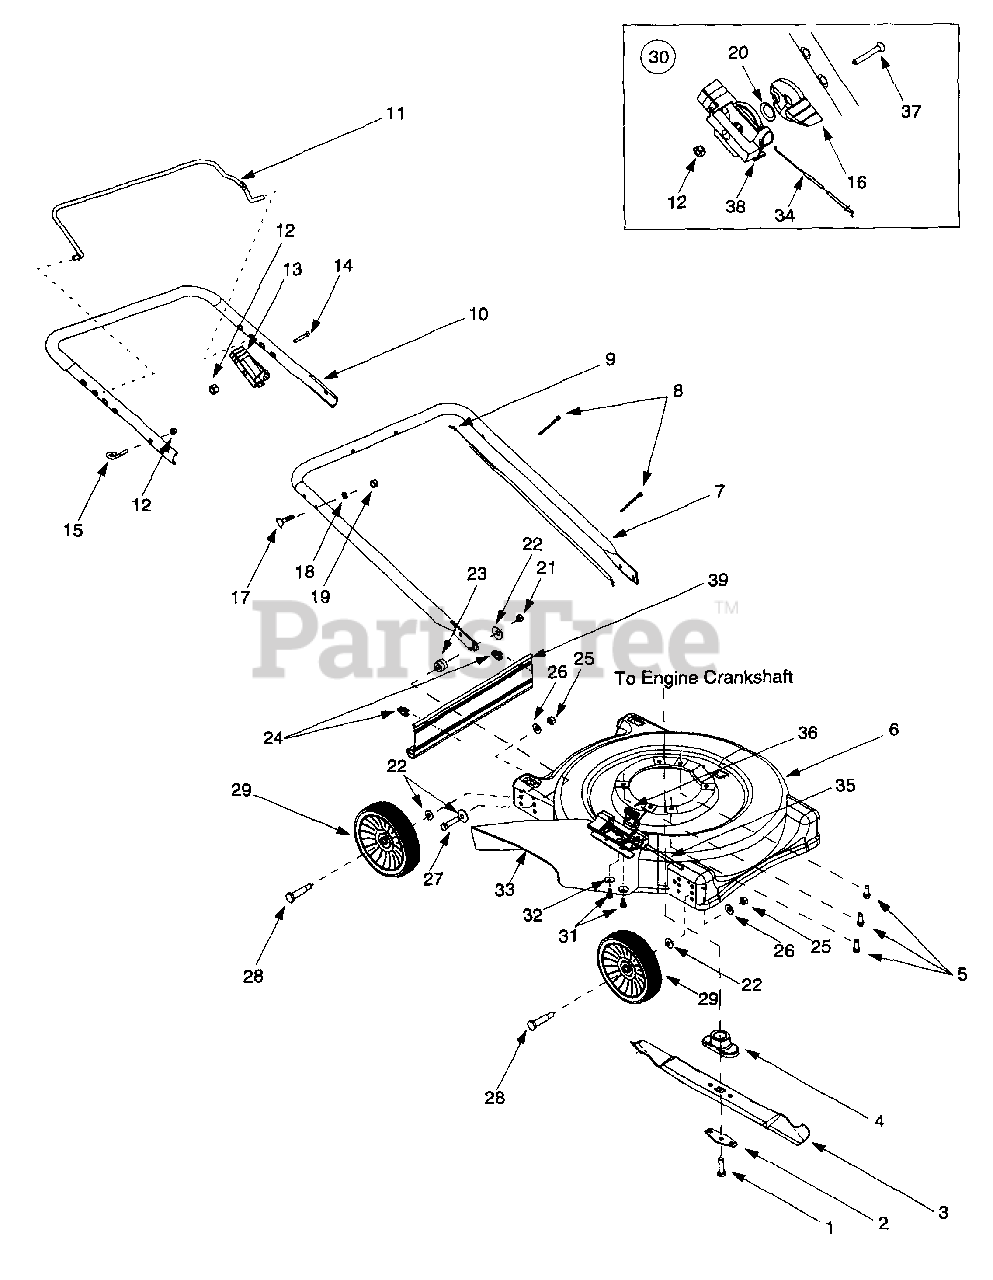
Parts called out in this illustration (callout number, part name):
1	Hex Bolt 3/8-24 x 1.5" Lg.
2	Support, Bell-Blade
3	22" Blade, Std.
4	Adaptor, Blade
5	Screw: TTSems, 3/8 - 16 x 1"
8	Cable Tie
9	Control Cable-39"
12	Hex L-Nut 1/4-20 Thd.
13	Control Cable Box
14	Oval C-Sunk Scr.
15	Rope Guide
16	Throttle Lever
17	Curved Carr. Bolt 5/16-18 x 1"
18	L-Wash. 5/16" 1.D.
19	Hex Nut 5/16-18 Thd.
20	Spring Washer
21	Hex L-Nut 3/8-24 Thd.
22	Bell Washer .380 ID x .88"
23	Spacer .391" I.D. x .375" Lg.
24	Hinge Clip
25	Hex Nut 3/8 - 16
26	Bell Washer .39 I.D. x 1.13
27	Hex Bolt 3/8 - 24 x 1.5
28	Axle Bolt
29	Wheel Assy
30	Throttle Box Complete
31	Hex Self-Tap Scr. 1/4-20 x .5"
32	Bell-Wash. 1/4" I.D.
33	Chute Deflector Ass'y
34	Throttle Cable, 51"
35	Hinge Pin
36	Torsion Spring
37	Oval C-Sunk Scr.
38	Throttle Body
39	Rear Trail Sheild
